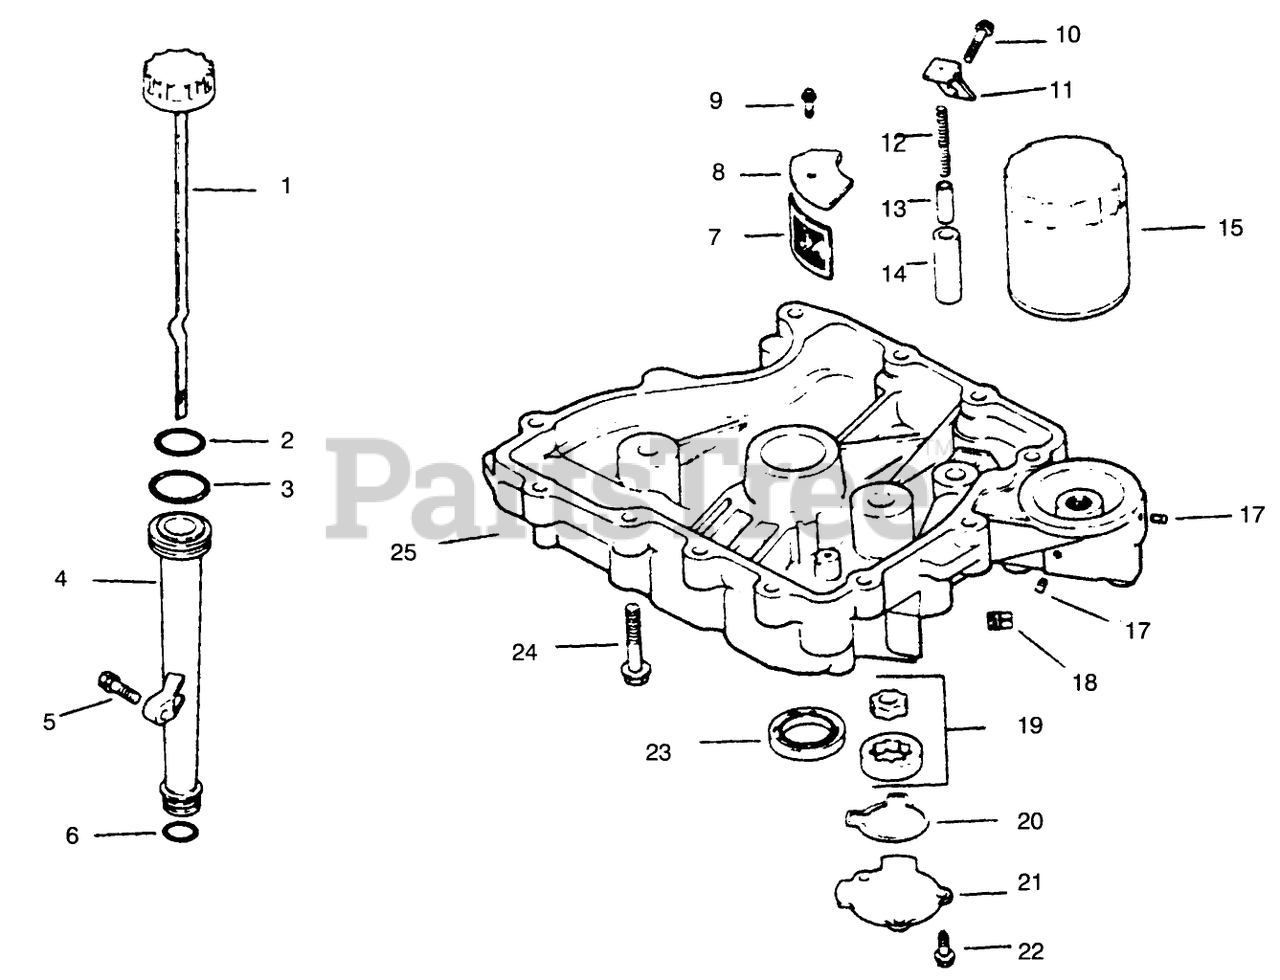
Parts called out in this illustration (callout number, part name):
1	Dipstick INC 2-3
2	"O"Ring
3	"O"Ring
4	Tube-Oil Fill
5	Screw
6	"O"Ring
7	Screen-Oil
8	Cover-Oil Screen
9	Screw
10	Screw
11	Bracket-Oil Pump Relief
12	Spring-Oil Relief Valve
13	Piston-Oil Relief Valve
14	Body-Oil Relief Valve
15	Filter-Oil
17	Plug-SH 1/8
18	Plug
19	Pump-Oil
20	"O"Ring-Pump Cover
21	Cover-Oil Pump
22	Screw
23	Seal-Crankshaft
25	Pan-Oil
